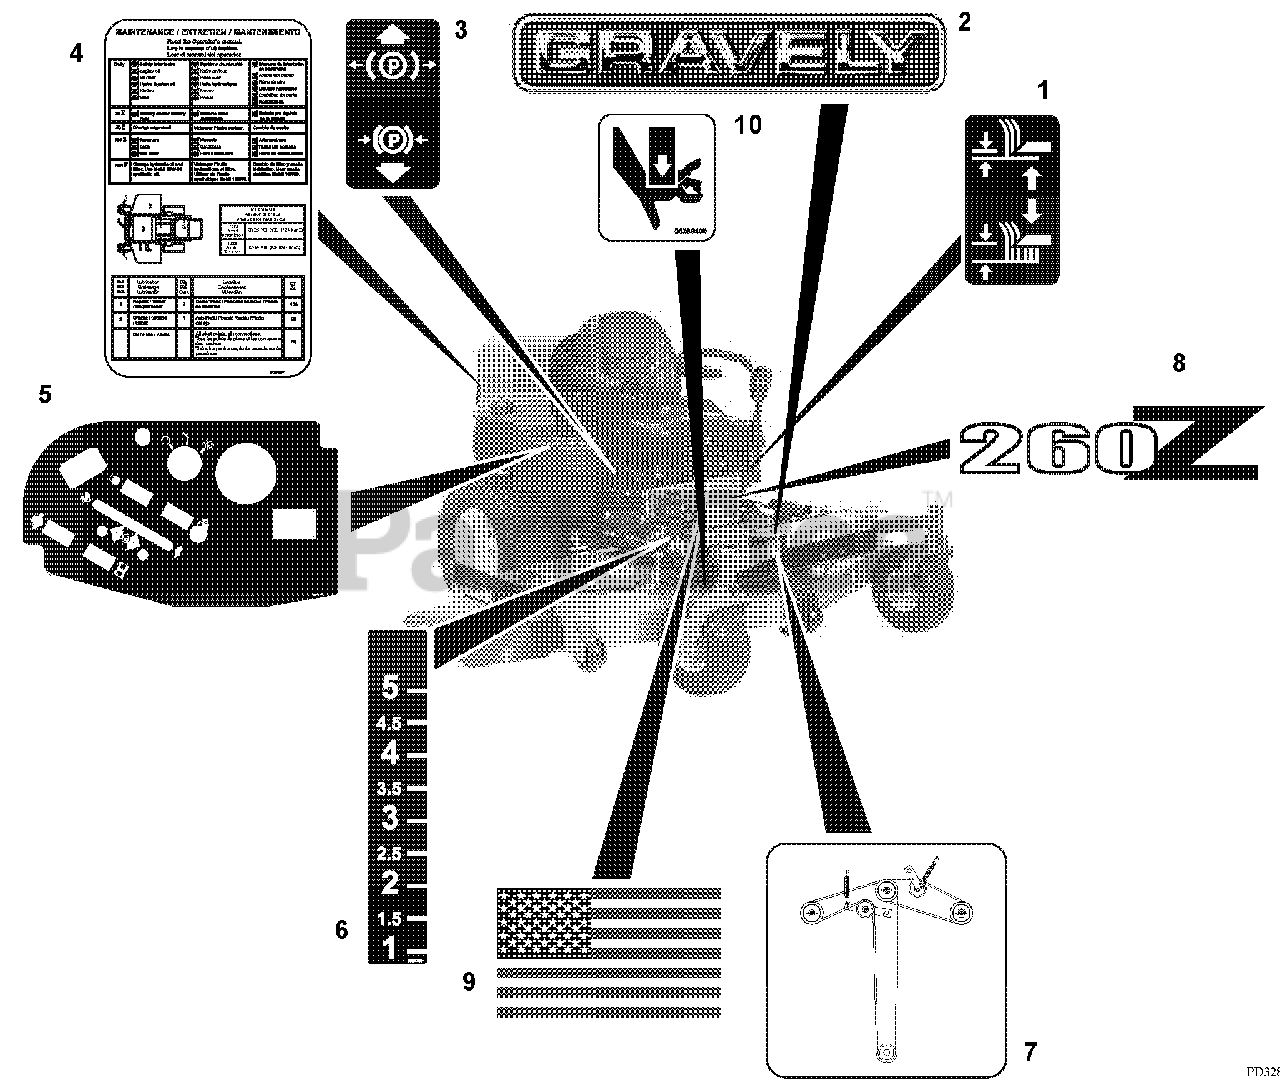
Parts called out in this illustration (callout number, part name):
1	Decal, Lift Lever
2	Decal, 15" Gravely Logo
3	Decal, Parking Brake Lever
4	Decal, Maintenance Instructions
5	Decal, Diesel Control Panel
6	Decal, Height of Cut
7	Decal, Belt Diagram
8	Decal, PM-260Z (992156)
9	Decal, American Flag
10	Decal, Pinch Point
